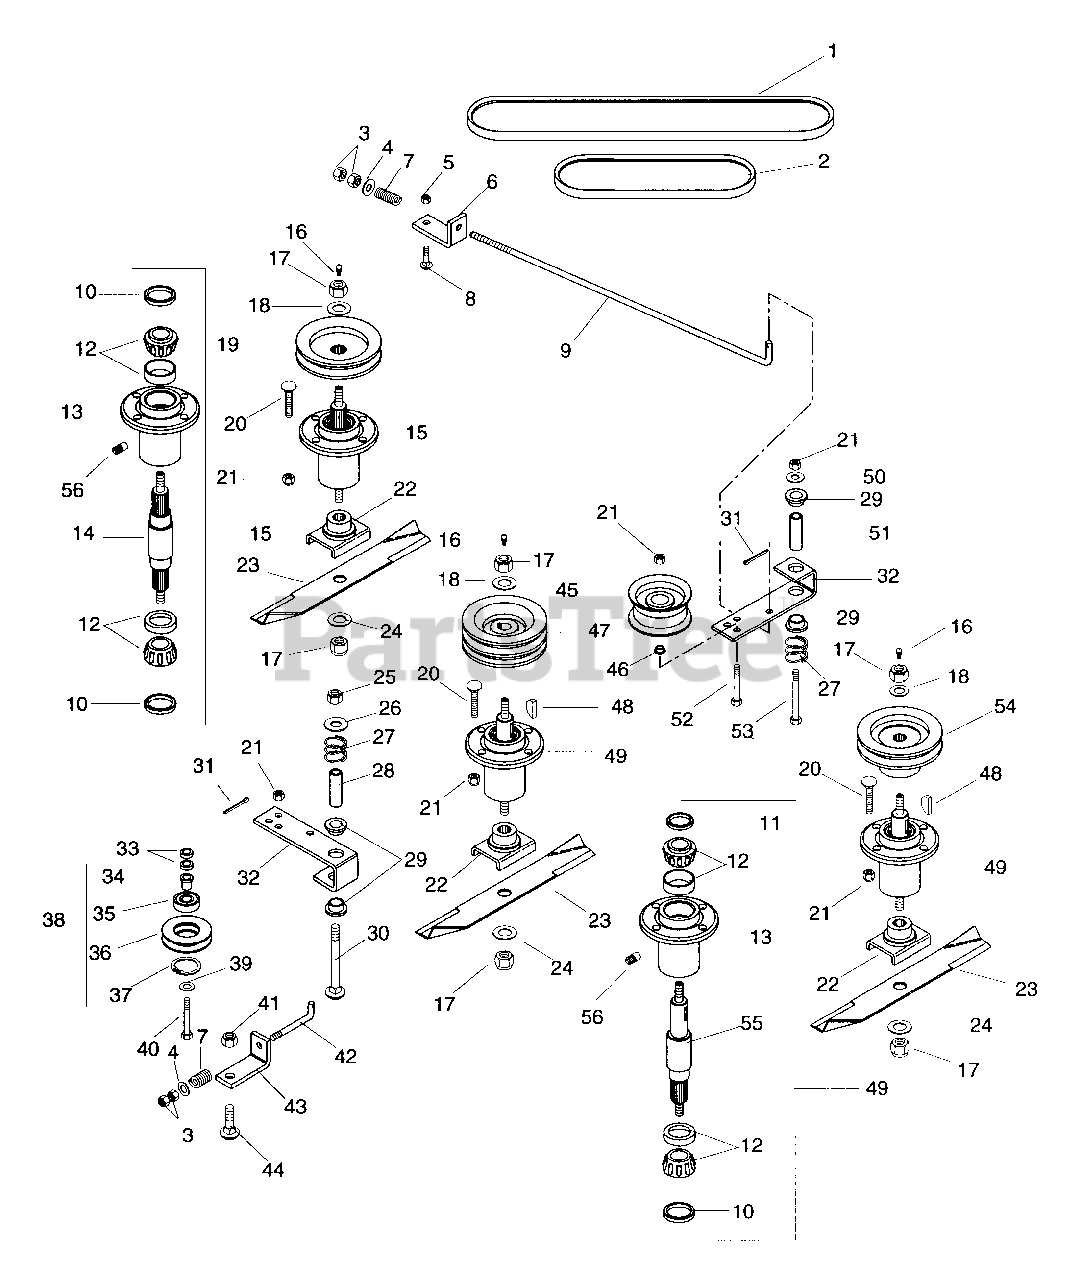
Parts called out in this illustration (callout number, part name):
1	Belt, Pro Mwr
2	Belt, Mower A44
3	Nut Hex .375 - 16
4	Wshr - Fl - Stl .281 x .625 x .065
5	Nut - Lk - Nyl .312 - 18 Pl
6	Brkt, Belt Tensioner
7	Spring-Compression .125 x .78 x 1.00
8	Bit, Carriage 5/16 - 18 x 1.0
9	Rod, Idler L.H.
10	Seal 1.987 x 1.375 x .313
11	Seal 1.987 x 1.500 x .313
12	Asm, Bearing Cup & Cone
13	Bearing Housing
14	Shft, Spindle
15	Service Kit Spindle Assembly
16	Ftg, Lube 1/8
17	Nut, Lk 5/8 - 11 Hex W/Insr
18	Wshr - Fl - Stl .687 x 1.312 x .135
19	Sheave
20	Blt - Rdhdsqnk .38 - 16 x 1.375
21	Nut - Lk - Nyl .375 - 16 Pl
22	Weldment Blade Cradle
23	Bld, 50 Inch Mower
24	Wshr - Fl - Stl .656 x 1.312 x .095 Pl
25	Nut - Lk .50 - 13 Hex Type N
26	Wshr - Fl - Stl .531 x 1.250 x .100
27	Sg - Comp
28	Bush., S .560 x .750 x 2.44 St
29	Bshg - Flg .762 x 1.0 x .580 x 1.48 NY
30	Blt - Rdhdsqnk .50 - 13 x 3.50
31	Pin - Cotr .09 x .75 Pl
32	Arm, Idler Pivot
33	Bushing .406 x .750 x .188
34	Bshg - Flg .786 x 1.0 x .79
35	Brg - Ball 1.85 x .787 x .55
36	Sheave, idler
37	Rg - Rtng - Int 2.054 x .062
38	Asm, Idler Sheave
39	Washer, Flt .375 x 1.125 x .065
40	Blt - Hex .38 - 16 x 2.00 Pl Gr 5
41	Nut - Lk Nyl .50 - 13 Pl
42	Rod, Idler
43	Brkt, Belt Tensioner
44	Blt - Rdhdsqnk .50 - 13 x 1.50
45	Idler - Flat 4 - .687 x .38
46	Bshg - Flg .406 x .88 x .270 x .140
47	Sheave
48	Key, Wdrf 1/4 x 1 Hrd #15
49	Service Kit Spindle Assembly
50	Wshr - Fl - Stl .438 x 1.000 x .083
51	Bush., S .437 x .750 x 2.44 St
52	Blt - Hex .38 - 16 x 2.25 Gr 5
53	Blt - Hex .38 - 16 x 3.25 Pl Gr 5
54	Sheave
55	Shft, Spindle
56	Relief Fitting
